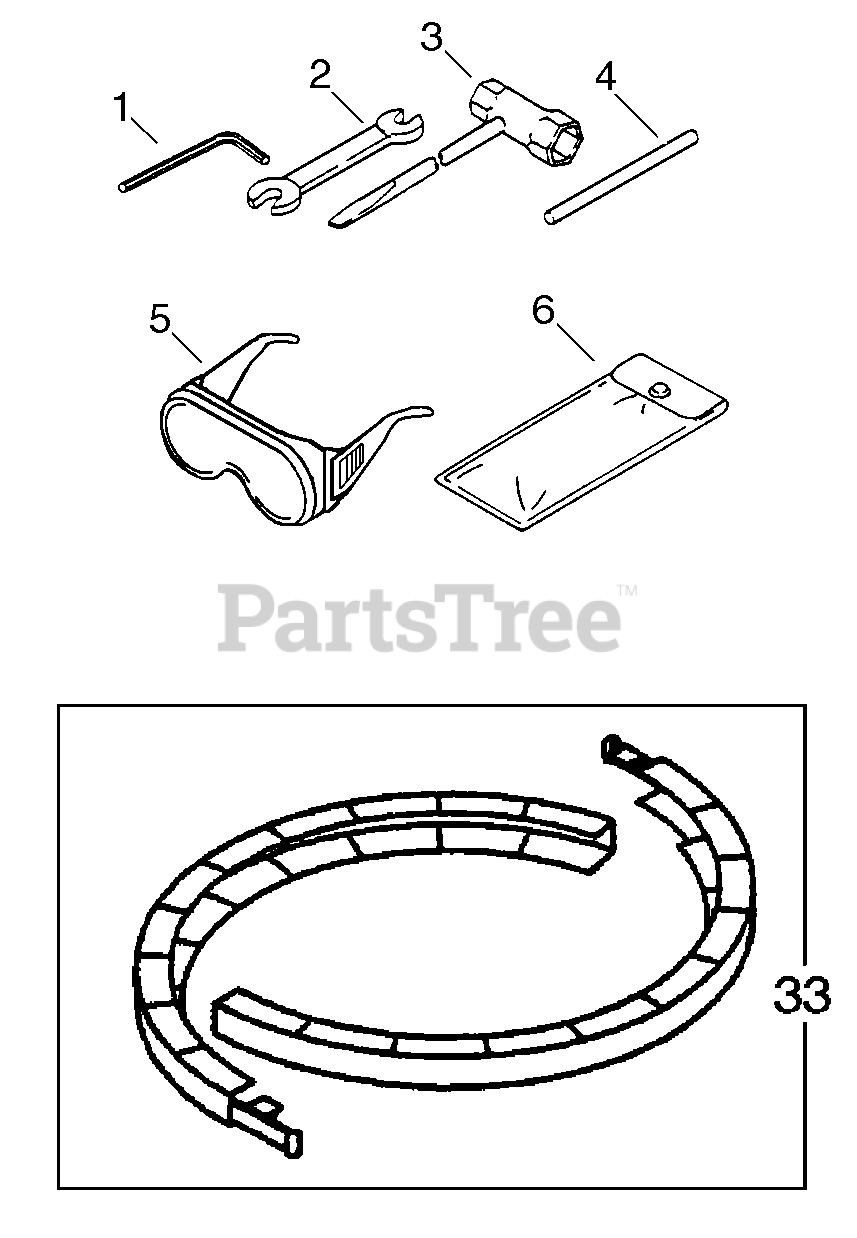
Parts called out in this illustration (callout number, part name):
1	HEX KEY - 4mm
2	SPANNER - 8X10mm
3	T-WRENCH - 17X19mm
4	ROD, LOCKING - 5X120mm
5	GOGGLES
6	BAG, TOOL
33	COVER, BLADE
